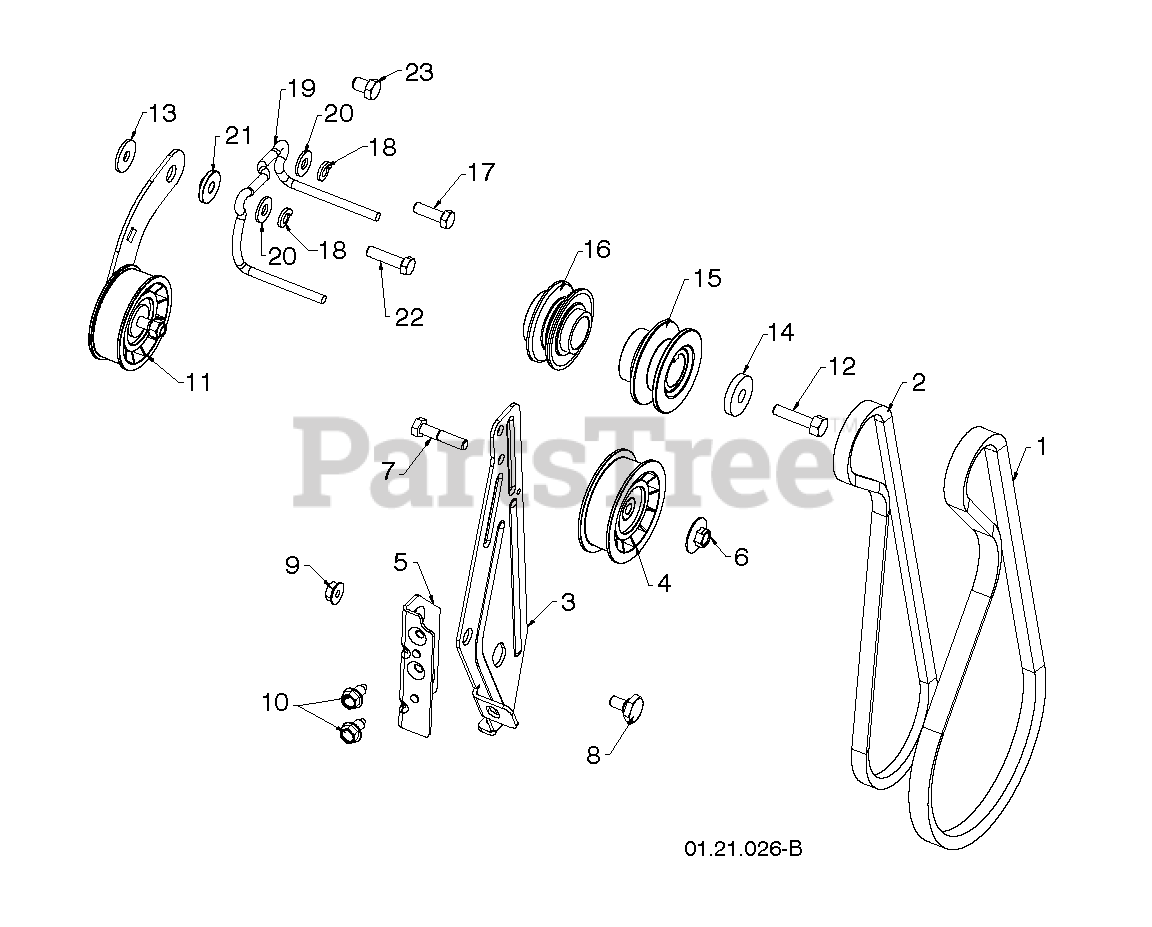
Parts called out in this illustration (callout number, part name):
1	V-BELT.IMPELLER
2	BELT.V.TRACTION.35.26
3	ARM.IDLER BRAKE.CLEAR.ZINC
4	PULLEY.W/SPACER.2.75
5	BRACKET.IDLER.PIVOT.ZINC
6	NUT.FLANGE.HEX.5/16X18.BLACK
7	HEX BOLT
8	BOLT.SHOULDER.1/2X12
9	NUT.LOCK.5/16-18
10	BOLT.5/16HEX.WHS.HD
11	ARM.ASM.TRACTION.IDLER.
12	BOLT.BLADE
13	STEEL WASHER
14	WASHER.400X1.25X5.
15	PULLEY IMPELLER.ASM.2.60_.75 B
16	PULLEY TRACTION.ASM.2.60_.75 B
18	LOCKWASHER
19	GUIDE.BELT.CHAIN.LS.SNOW
20	WASHER.20X8.5
21	BUSHING.BRAKE.ARM
22	CAPSCREW.HEXHD.5/16X1.25.
23	SCREW.3/8-16 X .750 (2 2)
